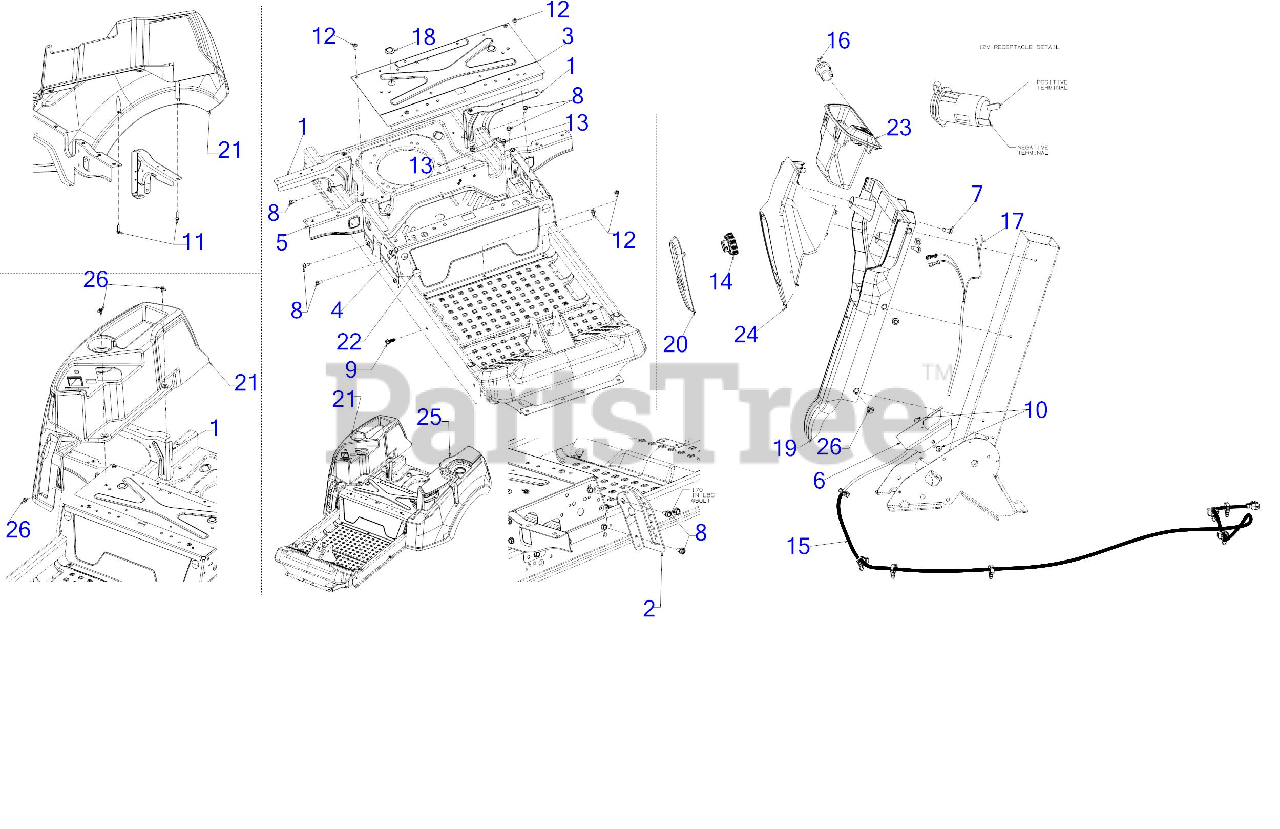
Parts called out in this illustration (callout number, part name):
2	HEIGHT INDEX BRACKET
7	SCREW 1/4-10:.625
8	SCREW 5/16-18 x .750
9	SCREW 3/8-16 x 1
10	SCREW 1/4-20 x .5
11	SCREW 5/16-14 x 1
12	SCREW 5/16-18 x .750
13	SCREW 5/16-18 x .500
14	HEADLIGHT ASSEMBLY
15	HEADLIGHT JUMPER HARNESS
16	12V RECEPTACLE
17	HEADLIGHT HARNESS CHARGE PORT
19	STEERING COLUMN COVER
20	HEADLIGHT LENS-LED
21	CONSOLE (RH)
22	PLASTIC PLUG
23	FRONT MODULE COVER
24	COLUMN COVER
25	CONSOLE (LH)
26	SHOULDER SCREW M6-1 .368 X.115
